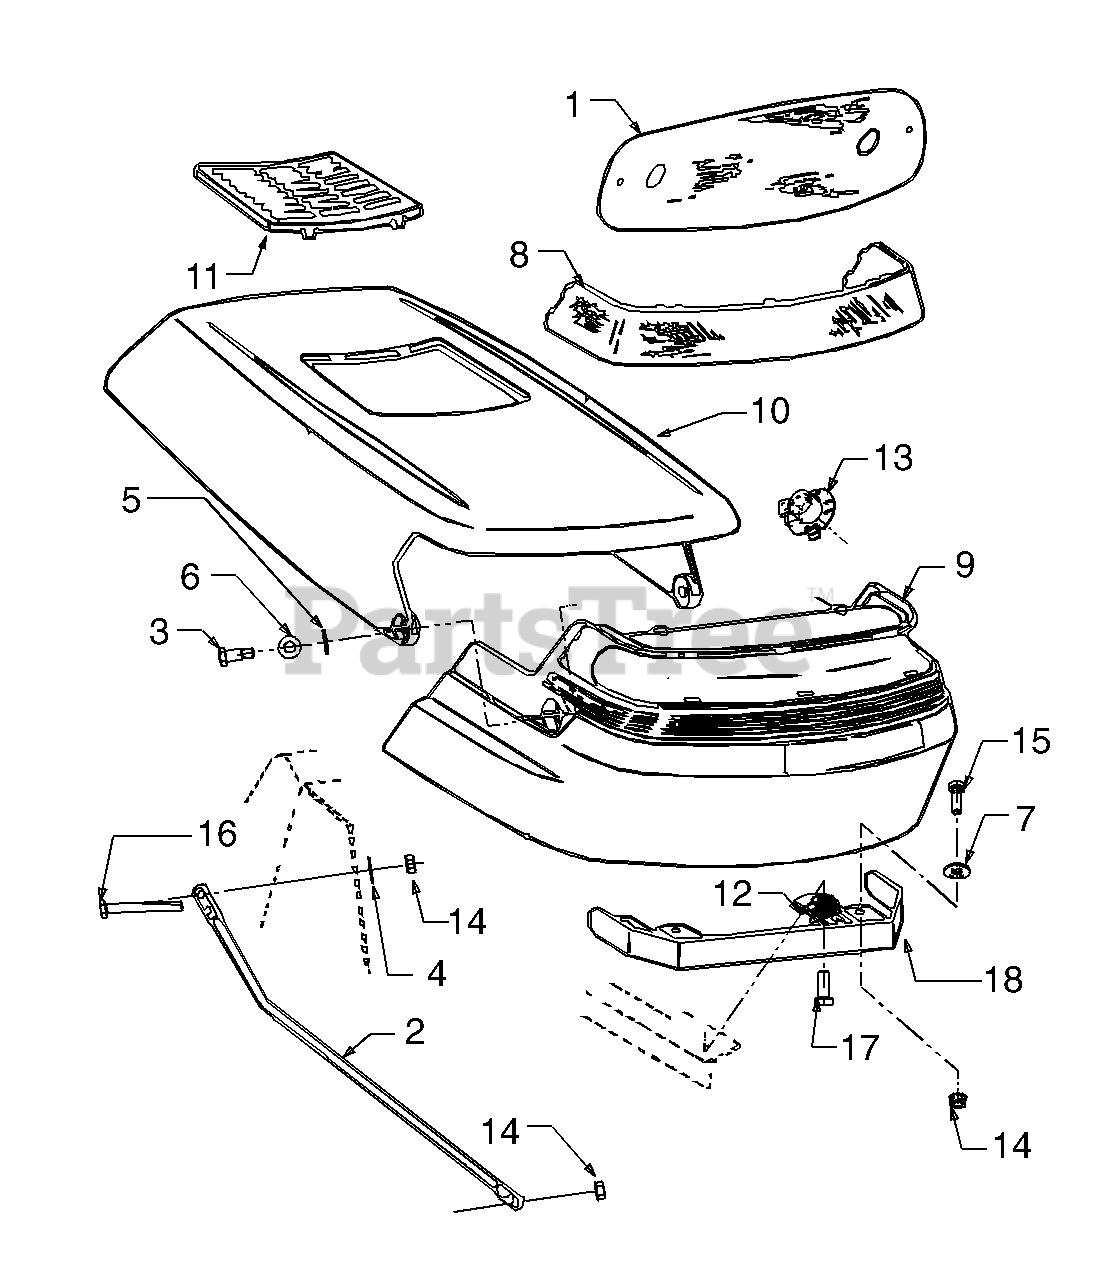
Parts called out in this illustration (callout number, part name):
1	Label
4	Flat Washer .283 x .75 x .030
5	Flat Washer 5/16
6	Spring Washer .317 x .625 O.D. x .099
7	Flat Washer .28 I.D. x .74 O.D.
8	Lens: G Style
9	Grille: G Style
10	Hood: G Style (MTD Red)
11	Louver Plate
12	U Nut
13	Lamp
14	Hex Nut 1/4-20
15	Hex Bolt: 1/4-20 x .75 Gr. 5
16	Hex Bolt 1/4-20 x .625
17	Hex Bolt 5/16-18 x .75
18	Grille Support Assembly
